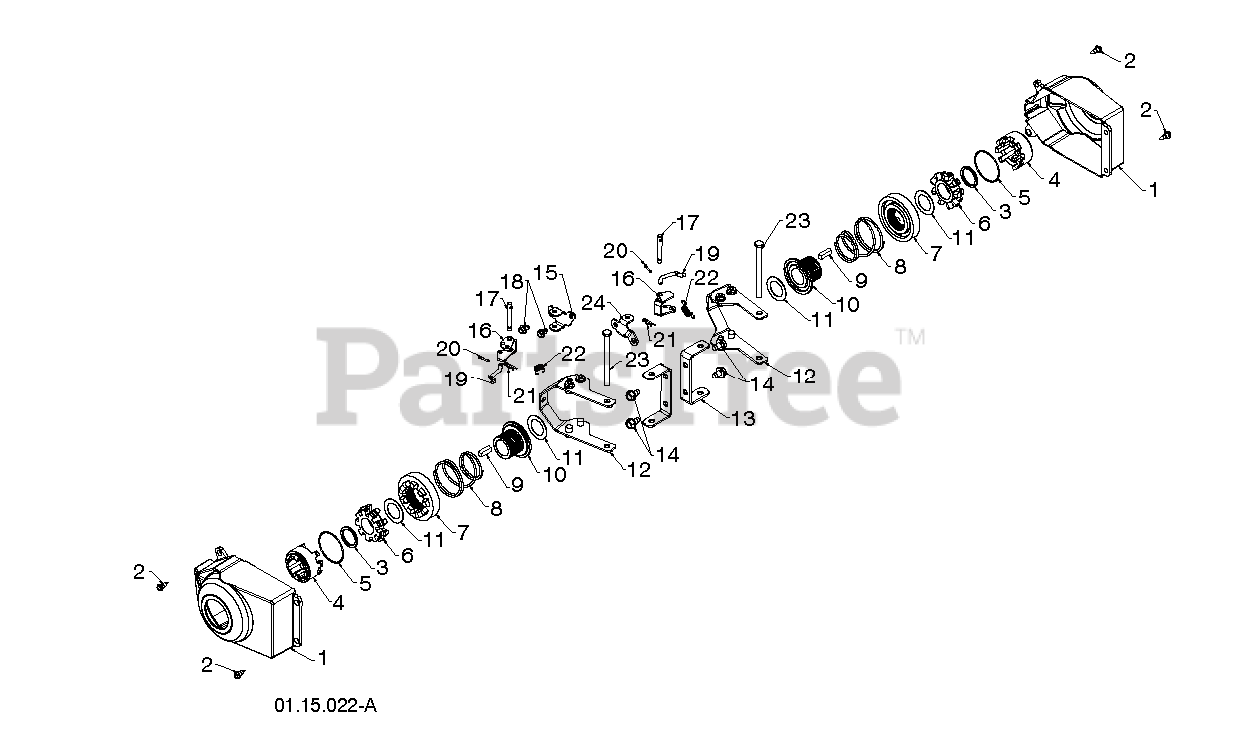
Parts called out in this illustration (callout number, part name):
1	COVER, POWER STEERING
2	SCREW, HEX HEAD, TAPPING
3	SPACER.POWER.STEERING TRACK
4	DRIVER.WHEEL.POWER.STEERING
5	RING, WIRE RETAINER
6	LOBE WHEEL
7	SLIDE.CLUTCH.SNOW
8	SPRING COMPRESSION TAPERED.PS
9	KEY, SQUARE 1/4 X .875
11	WASHER 1.00
12	YOKE.ASM.BOLT.BLACK
13	BRACKET.STEER.PNT.BLACK
14	Screw 5/16-18 x 1/2 Hex, Self Tapping 5/16-18 x 1/2
15	BRKT.STEER.PIVOT.RH
16	BELLCRANK.STEER
17	PIN, STEERING BELLCRANK
18	SCREW 1/4X20
19	LINK.STEER.YOKE
20	RETAINER CLIP
21	RETAINER CLIP PM
22	SPRING LATCH
23	PIN, STEERING LEVER
24	BRACKET.STEER.PIVOT.LH.YZ
